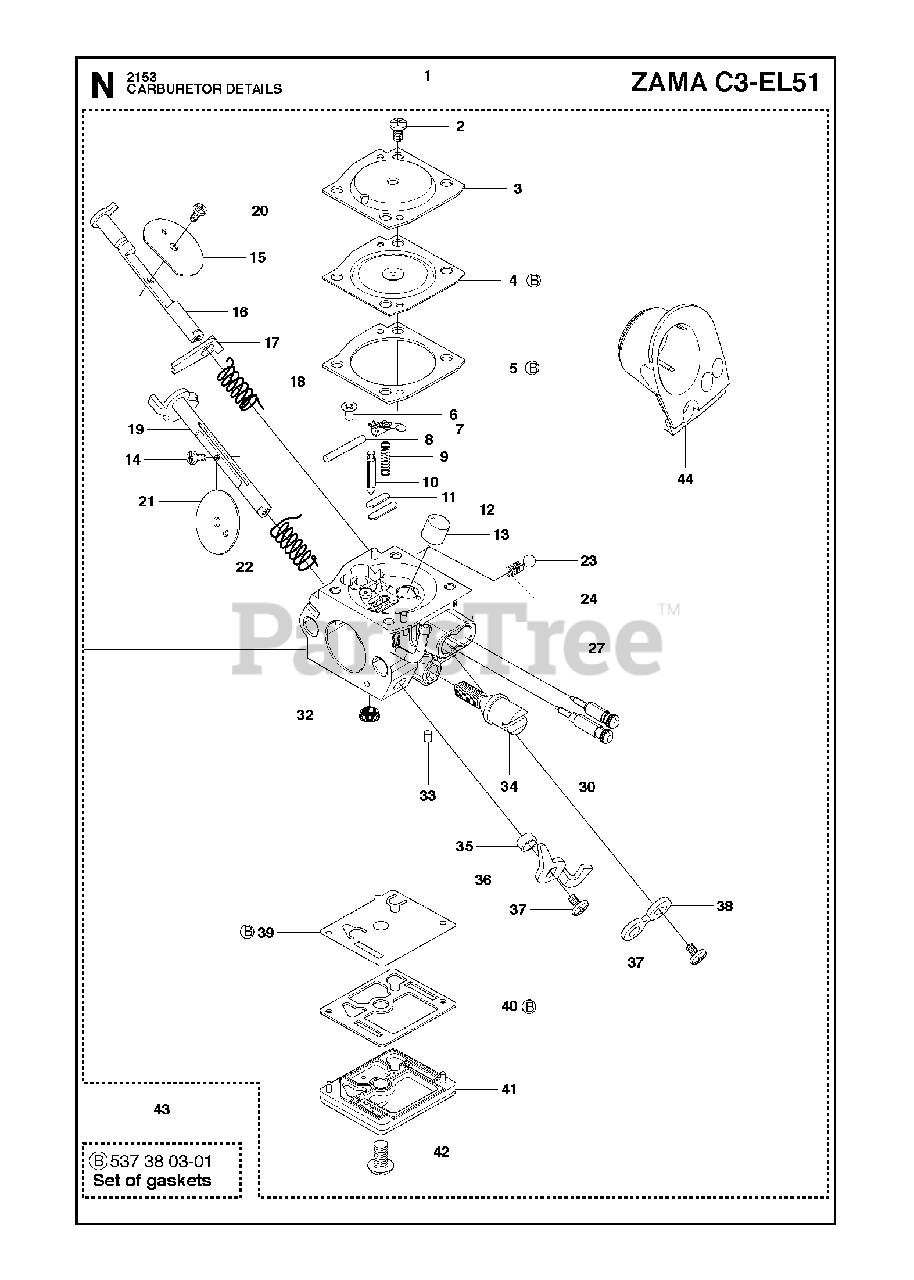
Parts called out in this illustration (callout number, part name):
2	SCREW
3	COVER
4	DIAPHRAGM
5	GASKET
6	SCREW
7	LEVER
8	PIN FULCRUM
9	SPRING
10	VALVE
11	PLUG
12	PLUG
13	JET
14	SCREW
15	CHOKE FLAP
16	CHOKE SHAFT
17	THROTTLE LOCK
18	SPRING
19	THROTTLE SHAFT
20	SCREW
21	THROTTLE FLAP
22	SPRING
23	BALL
24	SPRING
27	JET
30	LOW SPEED NEEDLE
32	STRAINER
33	PLUG
34	IDLE SCREW
35	BUSHING *
36	LEVER
37	SCREW
38	LEVER
39	PUMP DIAPHRAGM
40	GASKET
41	COVER
42	SCREW
43	GASKET SET
